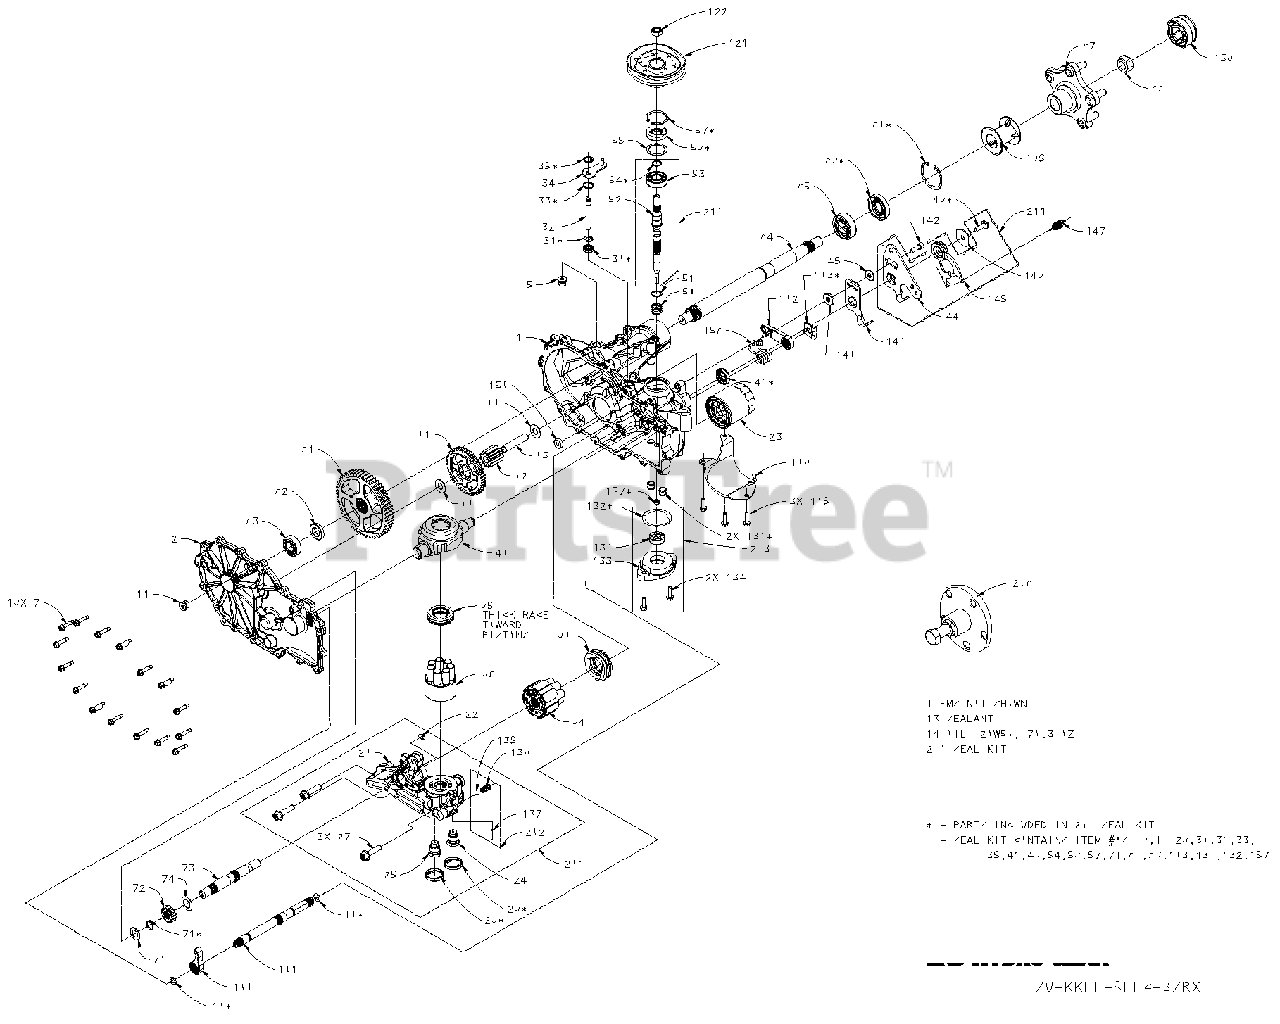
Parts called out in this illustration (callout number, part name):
1	KIT, HOUSING,MAIN,LH,CHRG,CNTL
2	KIT, COVER, SIDE, LH
5	PLUG 9/16-18 (METAL)
7	HFHCS 1/4-20 x 1.125"
10	O-RING - 111 .103 x 424
11	PLUG 9/16-18 (METAL)
13	SEALANT
22	PLATE, BYPASS
23	FILTER, OIL
26	SEAL, PLUG 1.250 x .250
27	HFHCS 3/8-16 x 1.5 (PATCH)
30	SEAL, LIP .375 x .75 x .25
31	RING, RET .375 EXTRNL
32	ROD, BYPASS
33	RING, RET .750 INTRNL
34	ARM, BYPASS
35	RING, RTNG .375 EXT
40	TRUNNION, SWASHPLATE
41	SEAL, LIP 12 x 32 x 7
45	WASHER .34 x .88 x .06
46	TWHCS 5/16-24 x 1.00 (PATCH)
50	SPRING, BLOCK
51	WASHER-FLAT .59 x .79 x .04
55	WASHER 1.23 x 1.56 x .04
56	SEAL, LIP 17 x 40 x 7
57	RING, RETAINING
60	BEARING, THRUST
64	ASS'Y, CYLINDER BLOCK, 16cc
65	BRG, THRUST PLASTIC CAGE
69	ASS'Y, BLOCK 7 PISTON
70	WASHER .63 x 1.0 x .05
71	RING, RETAINING_.625
72	GEAR, 13T, STEEL
73	SHAFT, MOTOR
74	WASHER .72 x 1.16 x .04
80	WASHER .5 x 1.0 x .03
81	GEAR, 46T
82	GEAR, 11T, STEEL
83	JACK SHAFT (PIN)
90	RING, RET 2.06 INT
91	GEAR, 54T
92	SPACER, .750 x 1.320 x .257
93	BEARING, BALL, .75 x 40 x 12
94	SHAFT, AXLE
95	BRG, BALL 25.4 x 52 x 15
96	SEAL, LIP 1.000 x 2.049 x .375
97	KIT, HUB, 5 BOLT
99	NUT, HEX LOCK 3/4-16
100	PAWL, BRAKE
101	SHAFT, BRAKE
102	KIT HANDLE, ACTUATING
103	CLIP, RETAINING
105	SCREW, HEX FLANGE 1/4-20 x .625
106	GUARD, FILTER, LH
121	PULLEY, 4.5 x 1.625
122	NUT,HEX JAM 1/2-20 W/ PATCH
130	TUBE, CONNECTING
131	GEROTOR ASSEMBLY (1.9 cc/rev)
132	O-RING, -137, 0.103 x 2.050
133	COVER, CHARGE PUMP
134	SCREW, HEX FLANGE 1/4-20 x .625
140	SPACER .320 x 1.005 x .179
141	ARM, NEUTRAL LEFT
142	SHCS 5/16-24 x 1 PATCH
146	WASHER, .343 x 1.500 x .062
147	SPRING, EXTNSN RTN-34LBS
157	SEAL, LIP 8 x 12 x 3 VC
158	MAGNET, RING
159	SPRING, TORSION CW
165	TUBE, AXLE 2.04
200	KIT, SEAL
201	KIT, CENTER SECTION, LH, CHRG
202	KIT, CHARGE RELIEF
203	KIT, CHARGE PUMP
209	HUB PULLER, 5 BOLT
210	KIT, INPUT SHAFT
